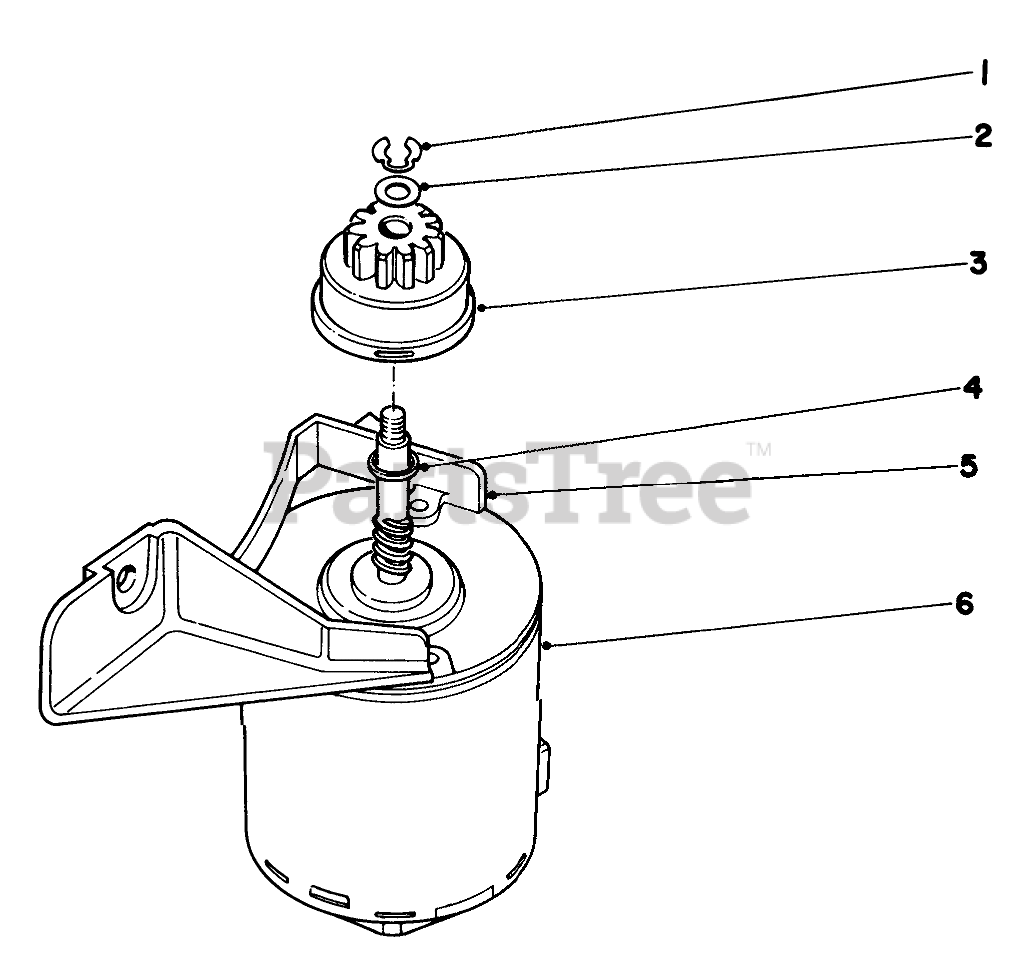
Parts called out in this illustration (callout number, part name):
1	RING-RETAINING
2	WASHER
3	PINION ASM
4	Spacer
5	Mounting Bracket
6	Starter Motor
